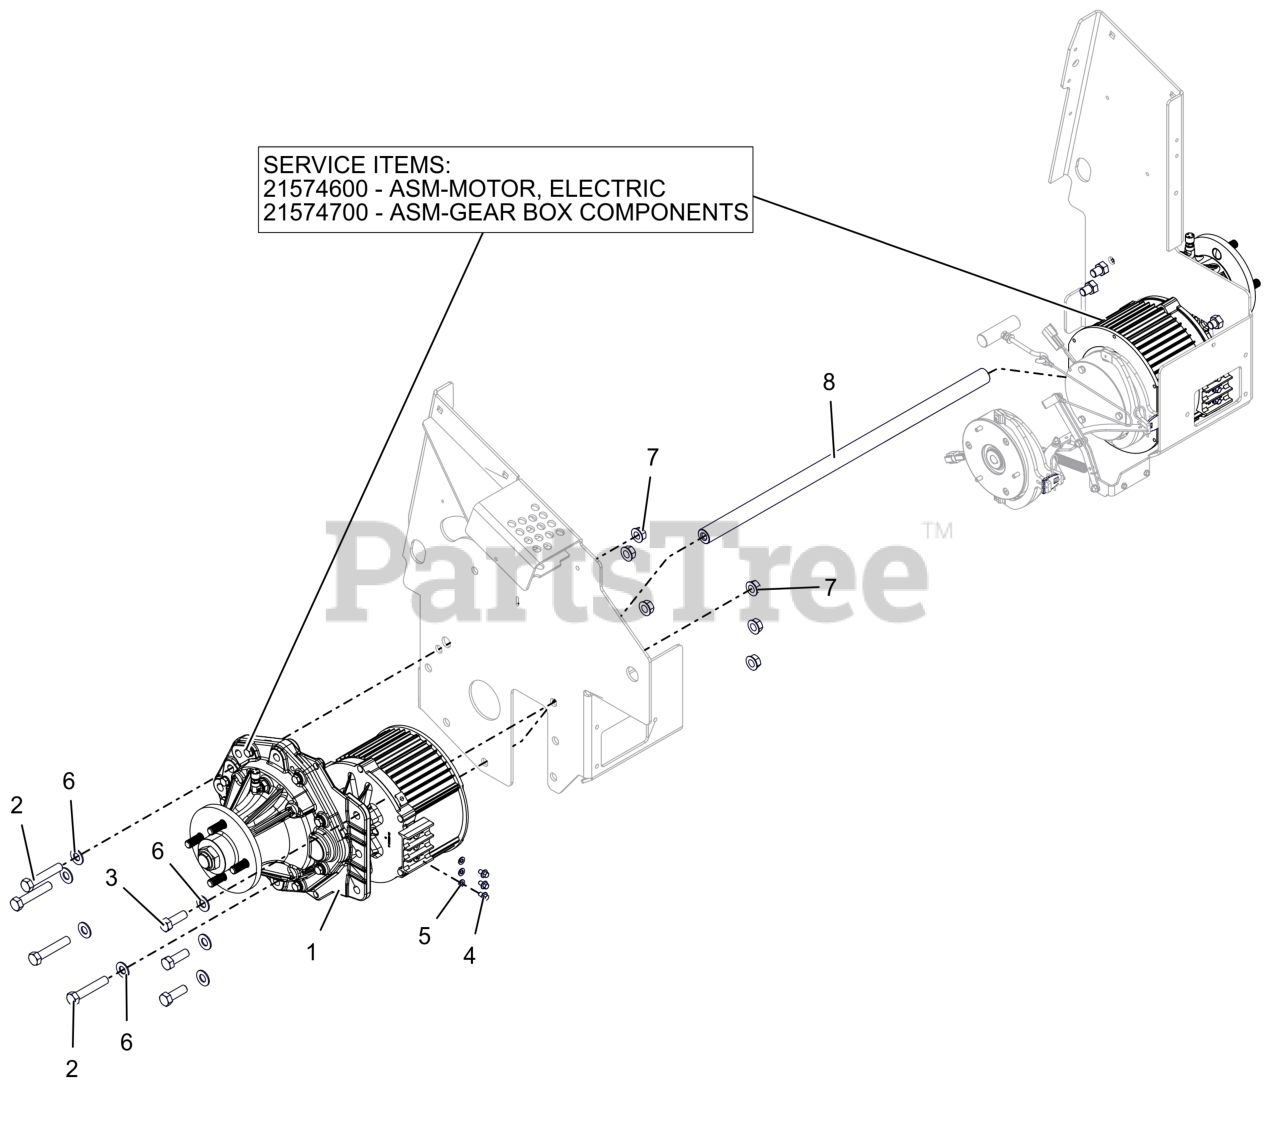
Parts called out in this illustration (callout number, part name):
1	ASM, WHEEL DRIVE
1	ASM-MOTOR, ELECTRIC
1	ASM-GEAR BOX COMPONENTS
2	BLT, HEX .50-13X2.75 G8 ZCC
3	BLT, HEX 0.5-13X1.5 GR8 ZCC
4	BLT,HEX M6-1X10 G8.8 ZCC
5	WSHR,LK-REG .250X.062 ZCC
6	WSHR, FLT .557X1.040X.102 ZCC
7	NUT, FLG-CTR LK .500-13 GG ZCC
8	SHAFT, TRANSAXLE SUPPORT (BLACK)
